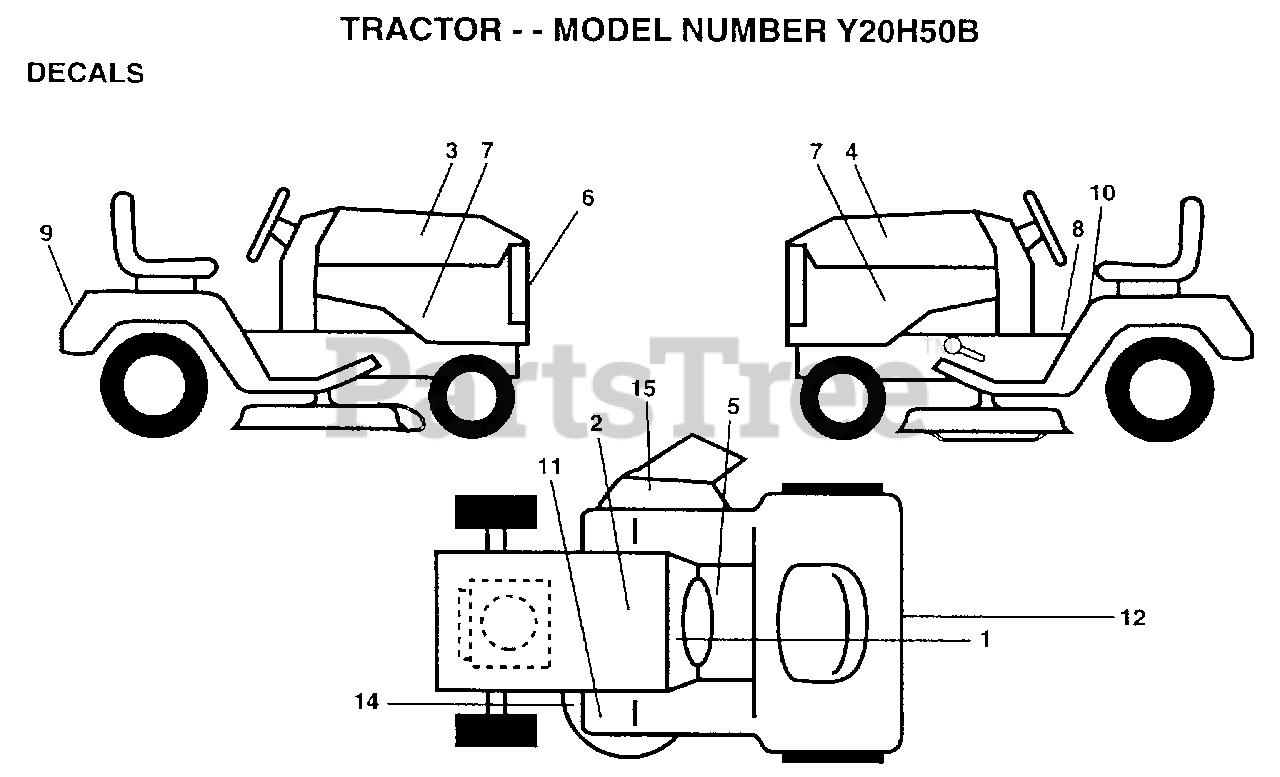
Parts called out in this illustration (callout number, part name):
1	DECAL.DASH.INSTR.
4	DECAL HOOD LH
5	DECAL BRAK PARK
6	DECAL.GRILL.YARDP
7	DECAL PANEL SIDE
8	DECAL SADL HYDRO
10	No Desciption for Part
12	DECAL D-BAR CNTRL
14	"DECAL.V.BELT.44"""
15	"DECAL, WARNING"
